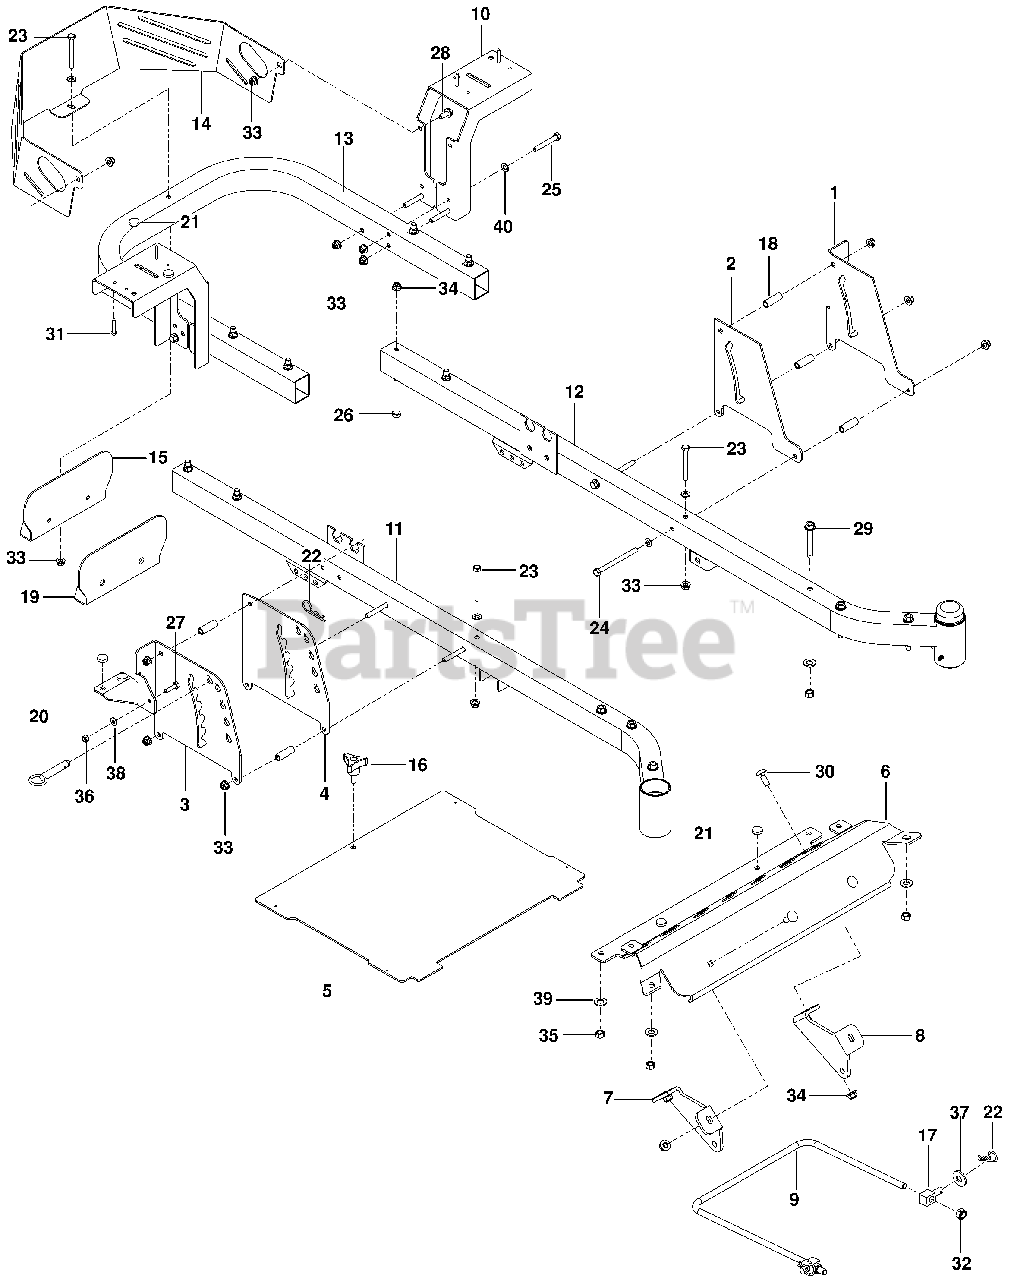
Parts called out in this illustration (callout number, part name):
1	PLATE, OUTER BRAKE, BLACK
2	PLATE, BRAKE LATCH, BLACK
4	PLATE, DECK HEIGHT, BLACK
5	PLATE, FOOT W/DECALS SPZ
6	FOOT REST, MED BLUE
7	MOUNT, STRUT, RT, BLK
8	MOUNT, STRUT, LT, BLK
9	LINK, FRONT SUSP.
10	SUPPORT, FENDER, BLACK
11	FRAME, RT, BLUE
12	FRAME, LT, BLUE
13	FRAME TUBE, REAR, BLUE
14	GUARD, REAR BLUE
15	PLATE, HITCH BLU
16	KNOB W/STUD
21	GROMMET, BUMPER
22	HAIRPIN #4
23	HCS 5/16C X 2-3/4
24	HCS 5/16C X 4
25	CAPSCREW
26	HCS 3/8C X 3
27	HCS 1/4C X 1
28	HHFS 5/16-18 X 3/4
29	HHFS 3/8-16 X 2 3/4
30	RHSNB 3/8C X 1
31	SCR #10-12X1-1/2HEX WASH HD ZD
32	7/16-14 HEX NUT W/NYL RING ZD
33	5/16-18 NYLOC FLANGE NUT
34	NUT 3/8-16 HEX FLG NYLOC ZD
35	NUT HEX 3/8-16 NYLON, THIN
36	NUT 1/4-20 NYLOC
37	WASH USS FLAT 1/2
38	WASHER 1/4 SAE
39	WASHER 3/8 FLAT
40	FLAT WASHER 5/16 SAE
